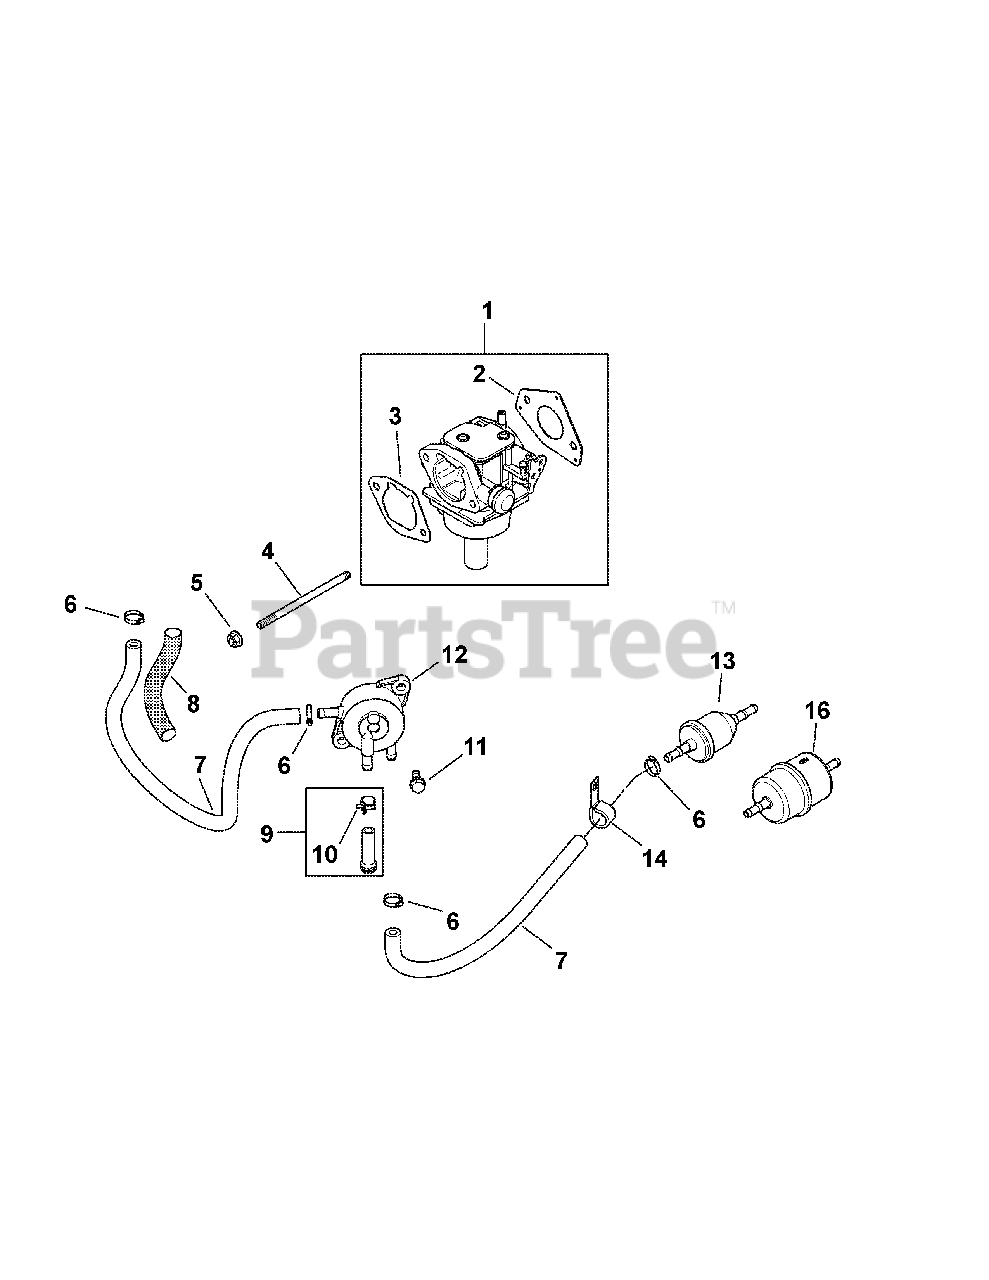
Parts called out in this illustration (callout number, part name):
1	Carburetor Kit, 22mm KEIHIN
4	Stud, M6 x 1.0 x 106
5	Flg. Nut, M6 x 1.0
6	Hose Clamp, 1/2
7	Fuel Line
8	Not used in this application
10	Not used in this application
11	Tap Screw, M6 x 1.7 x 18
16	Not used in this application
